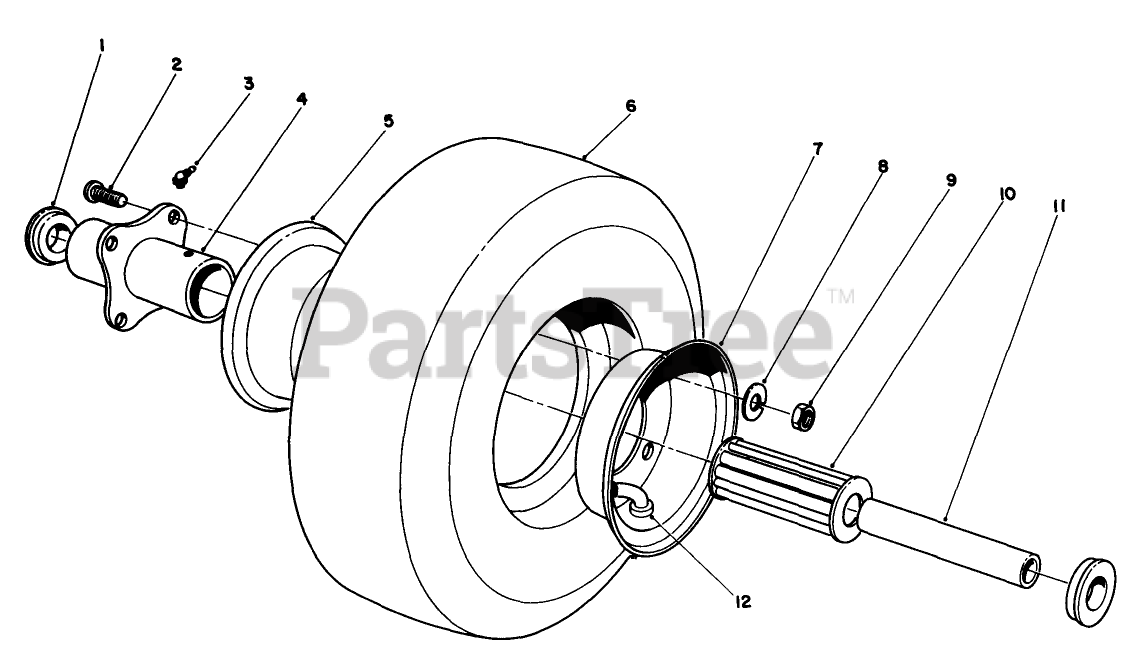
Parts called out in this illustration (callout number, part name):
1	RETAINER
2	WHEEL BOLT
3	FITTING-GREASE
4	HUB-CENTERED
5	WHEEL HALF-FEMALE
6	TIRE-10 INCH (2-PLY)
7	WHEEL HALF-MALE
8	WASHER-LOCK
9	NUT-HEX
10	ROLLER BEARING
11	SPANNER-BUSHING
